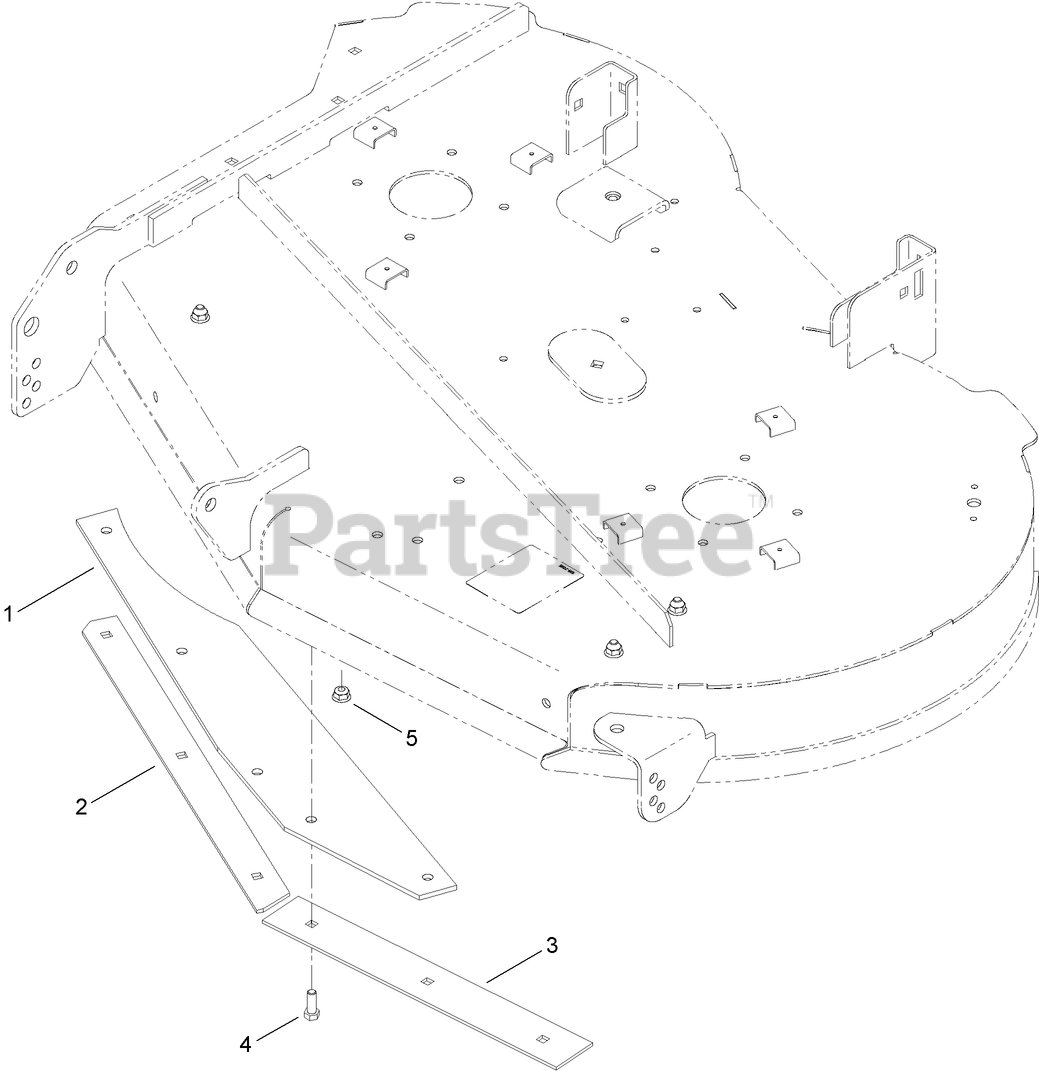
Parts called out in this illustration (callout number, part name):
1	SKIRT-RUBBER
2	PLATE-RH
3	PLATE-LH
4	SCREW-HH
5	NUT-HF, NI
